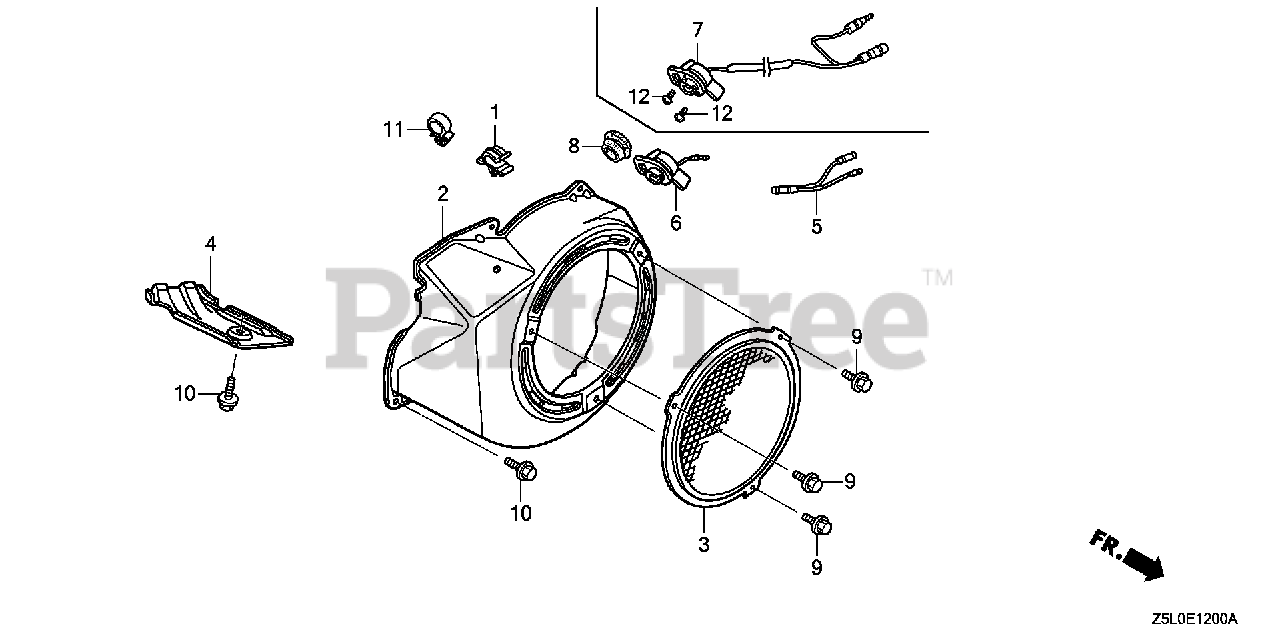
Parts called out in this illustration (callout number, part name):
1	CLIP, TUBE
2	COVER, FAN *R280* (POWER RED)
6	SWITCH ASSY., ENGINE STOP
10	BOLT, FLANGE (6X12) (CT200)
